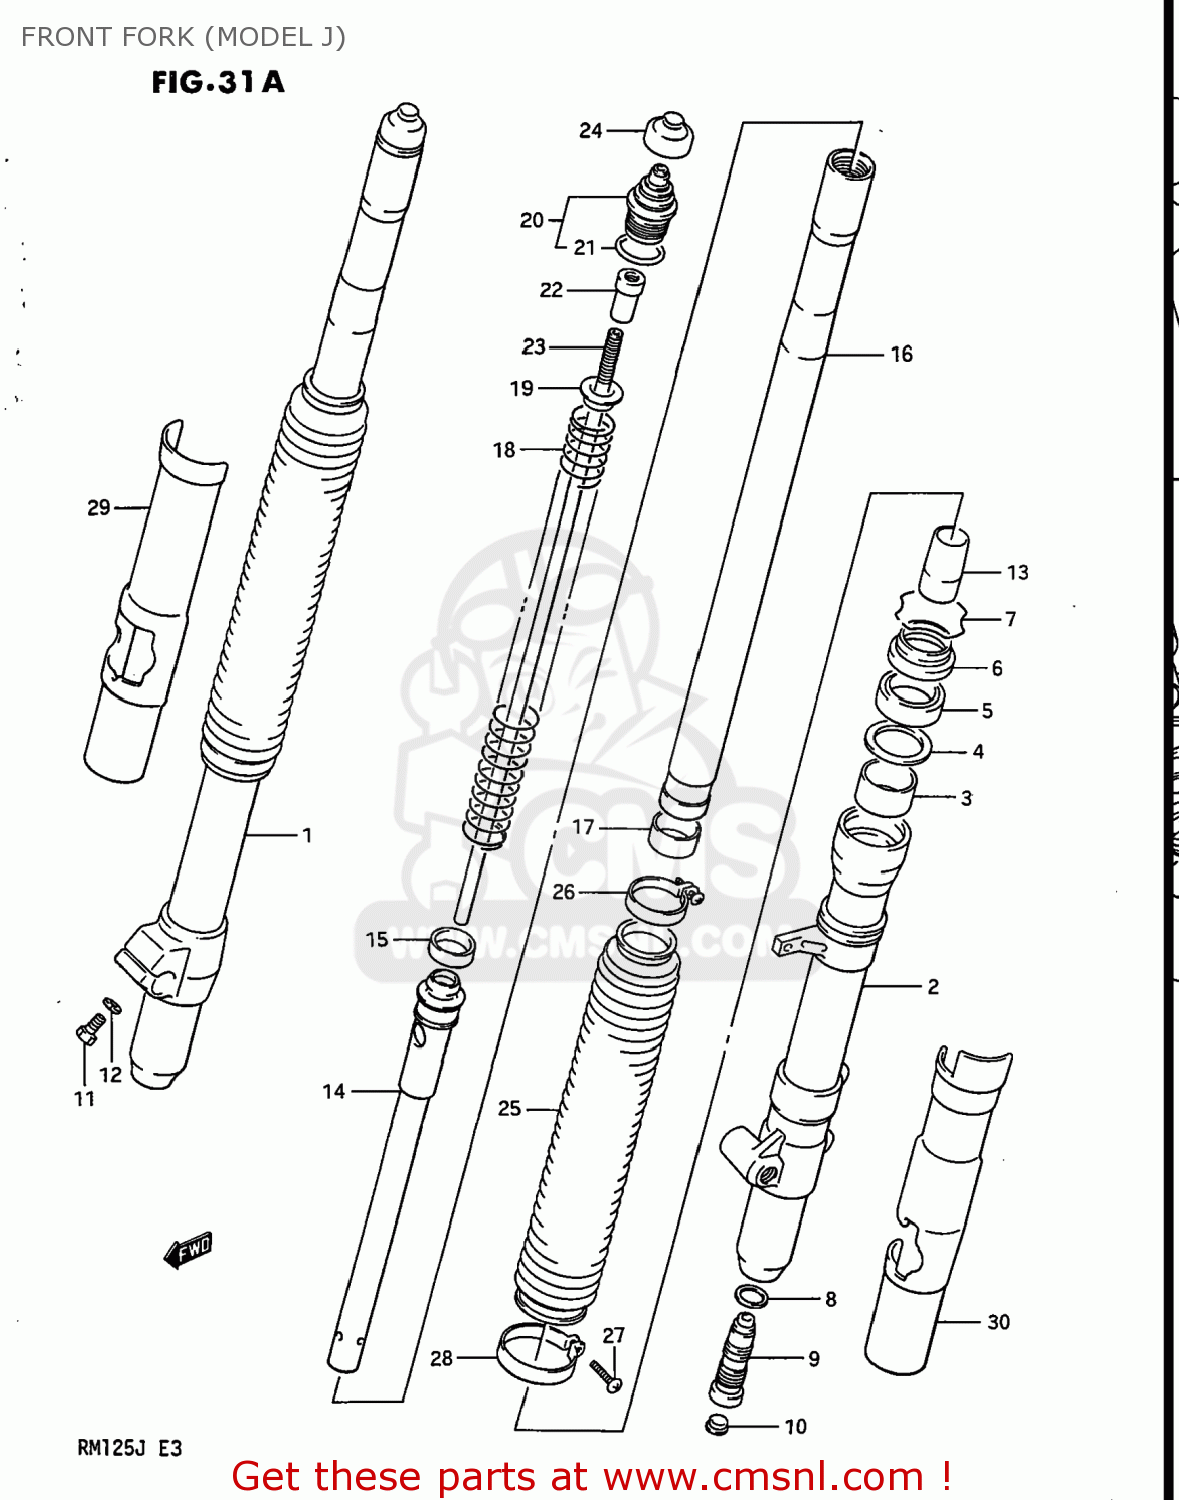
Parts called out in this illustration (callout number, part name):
1	TUBE,OUTER,RIGHT
2	TUBE,OUTER,LEFT
3	METAL,SLIDE
4	WASHER
5	OIL SEAL,FRONT FORK
6	DUST SEAL,FRONT FORK
7	RING,STOPPER
8	GASKET (NAS)
9	VALVE
10	CAP,FRONT FORK DF
11	BOLT
12	LOCK WASHER
13	PIECE,OIL LOCK
14	CYLINDER,FRONT FORK
15	RING,FRONT FORK PISTON
16	TUBE,FORK,INNER
17	PISTON
18	SPRING,FRONT FORK
19	GUIDE,FRONT FORK SPRING
20	CAP
21	O RING
22	NUT
23	ROD,PISTON
24	CAP
25	BOOT
26	BAND,BOOT UPR
27	SCREW,BAND BOOT(3.5X10)
28	BAND,BOOT LWR
29	PROTECTOR,RIGHT
30	PROTECTOR,LEFT
